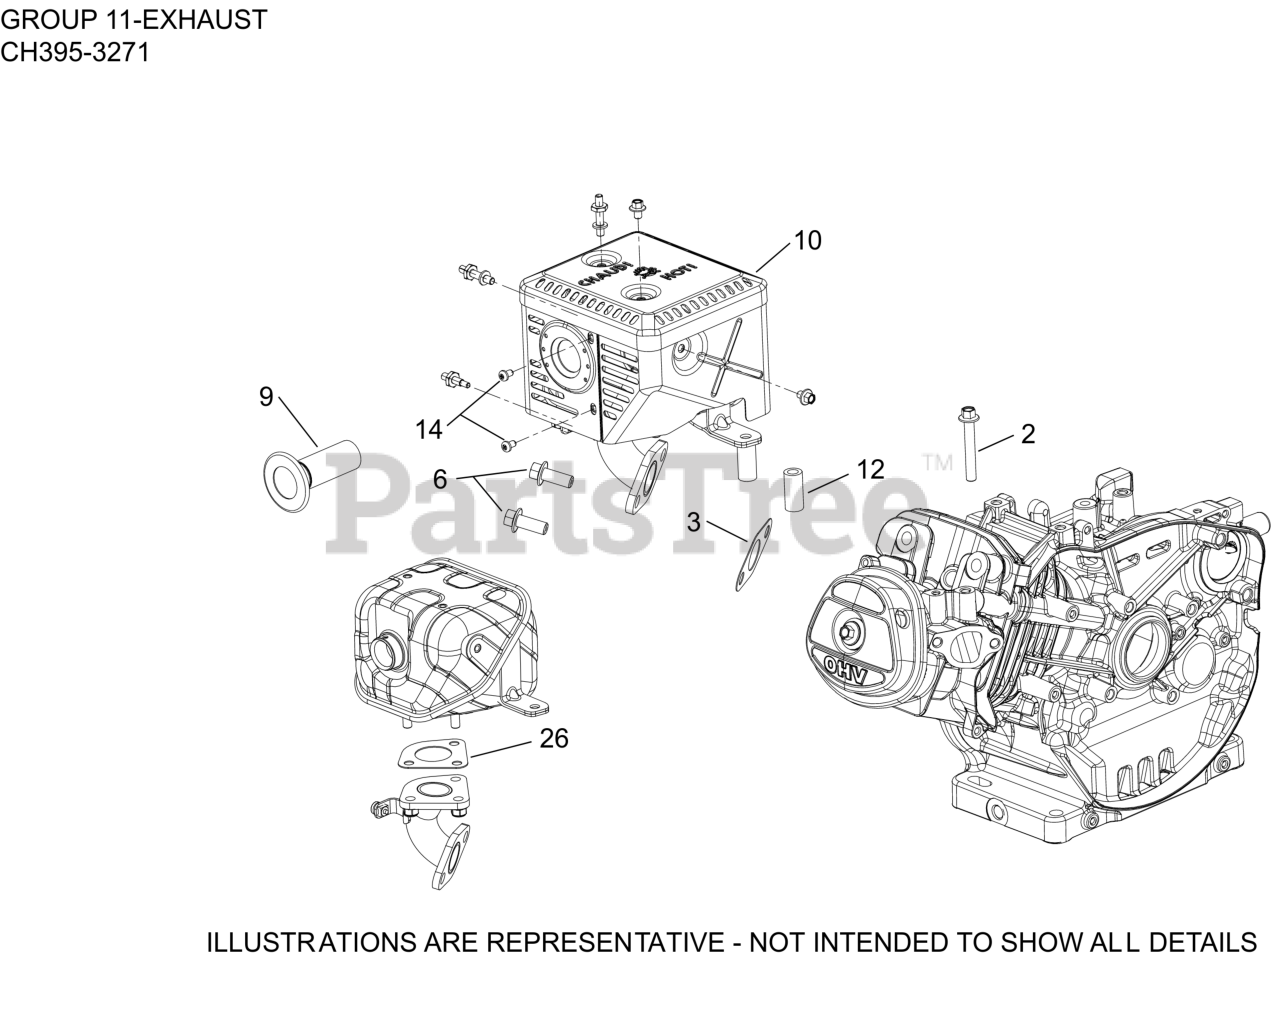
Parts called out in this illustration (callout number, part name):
2	SCREW, M8 X 55
3	GASKET, MUFFLER
6	SCREW, M10 X 25
9	ARRESTOR ASSEMBLY, SPARK
10	MUFFLER ASSEMBLY W/HEAT SHIELD
12	POST, MUFFLER BRACKET
14	SCREW, M5 X 8
26	GASKET, MUFFLER
